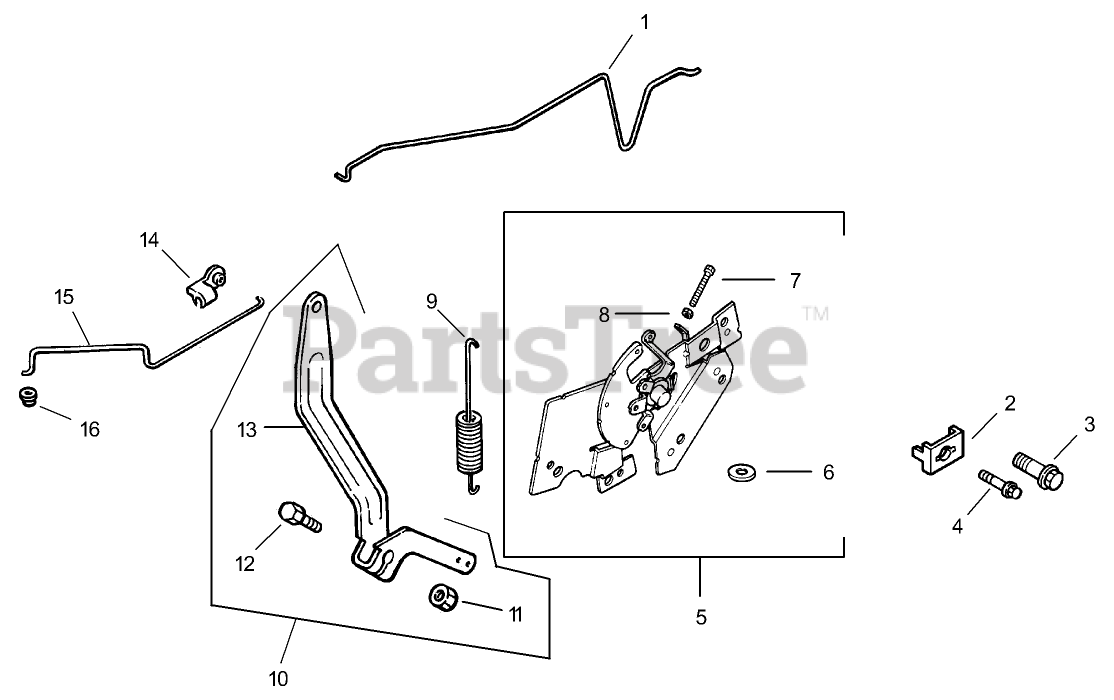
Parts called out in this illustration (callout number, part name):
1	Linkage-Choke
2	CLAMP-CABLE
3	SCREW-FLANGE, THREAD FORMING (M5X0.8X16)
4	Screw-Socket, 6 Lobed (Thread Forming, M6x1.0x20)
5	Control, speed assembly (Incl. 6-8)
6	Spacer-Shim
7	Screw (M4x0.7x30)
8	NUT (M4X0.7)
9	Spring-Governor
10	Kit, governor lever (Includes 11-13)
11	Nut-Flange, Hex (1/4-20)
12	Bolt-Square Neck, Round Head (1/4-20x1)
13	Lever-Governor
14	BUSHING-RETAINING, LINKAGE
15	Linkage-Throttle
16	BUSHING-LINKAGE, THROTTLE
